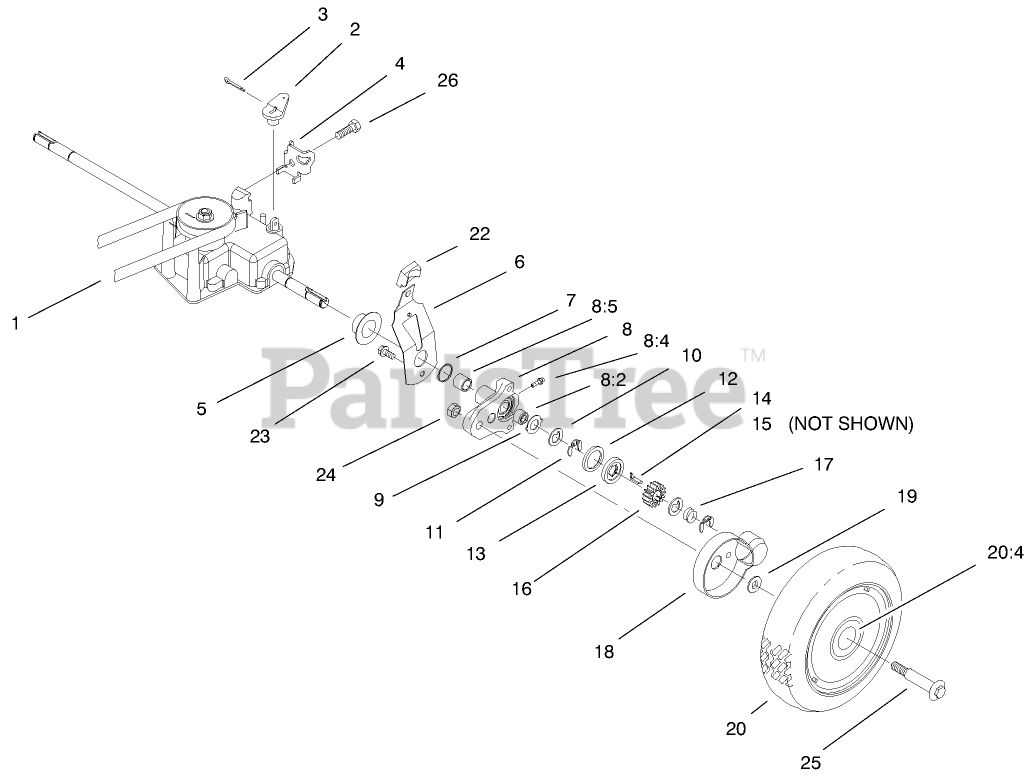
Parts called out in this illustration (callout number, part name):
1	V-BELT
2	LEVER-SHIFT
3	PIN-COTTER
4	CLAMP-CABLE
5	CAP-END
6	SPRING ARM ASM
7	O-RING
8	PIVOT ARM ASM
8:4	FITTING-GREASE
8:5	BUSHING
9	WASHER-ARM, PIVOT
10	WASHER-THRUST, KEYED
11	RING-RETAINING,CLIP
12	RING-FRICTION
13	WASHER-CLUTCH
14	KEY-ROCKING, LH
15	KEY-ROCKING, RH
16	GEAR-PINION
17	SPRING-COMPRESSION
18	COVER-WHEEL
19	SPACER-COVER, WHEEL
20	WHEEL TIRE ASM (SP)
20:4	BUSHING
22	KNOB-ARM
23	SCREW-HWH
24	LOCKNUT
25	BOLT-SHOULDER
26	SCREW-HWHTF
